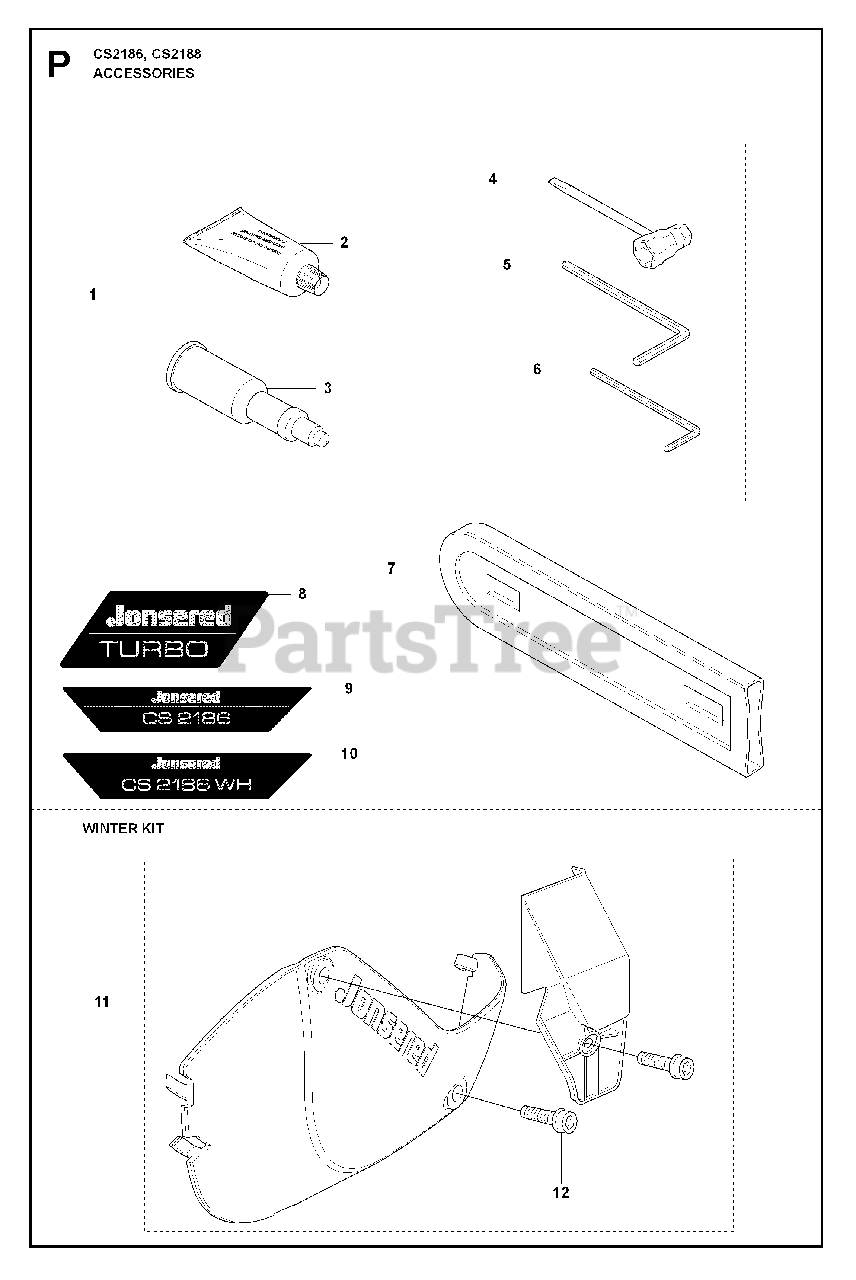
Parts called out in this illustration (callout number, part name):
1	TOOL KIT
2	GREASE
3	GREASE GUN
5	L-SPANNER
6	L-SPANNER
7	BAR COVER
11	PROTECTOR
12	SCREW
